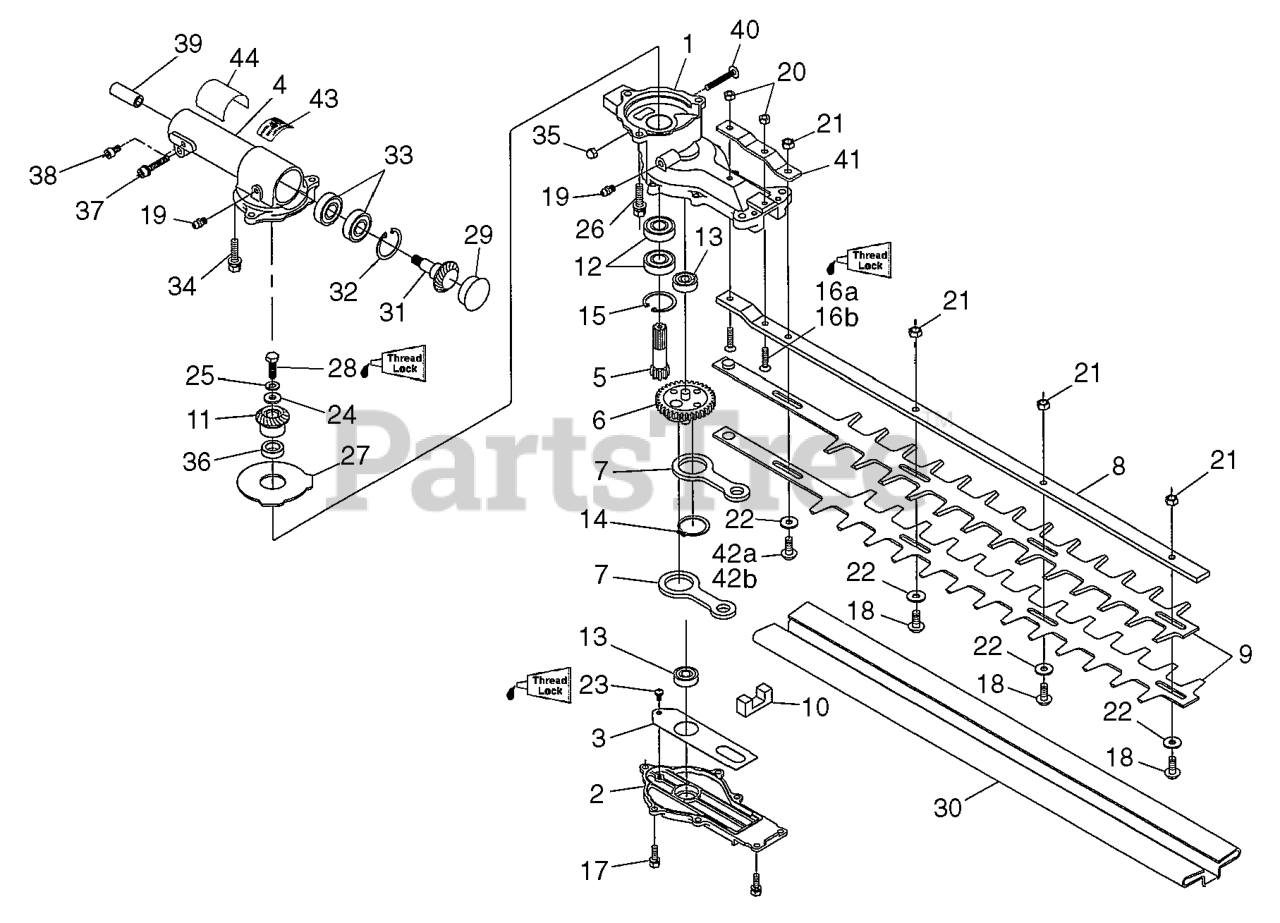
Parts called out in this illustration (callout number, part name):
1	CASING A
4	CASING (REPLS -61A0)
5	PINION GEAR
6	CRANK GEAR
8	GUIDE PLATE
11	BEVEL GEAR A
13	BEARING
14	SNAP RING
17	SCREW
18	SCREW(R3873,388411750&11770
20	U NUT M5
23	SCREW
31	BEVEL GEAR B
32	RING,SNAP M26x1.2 RP-318013340
34	BOLT M6X25
38	BOLT, M5 x 12
41	REINFORCEMENT PLATE
